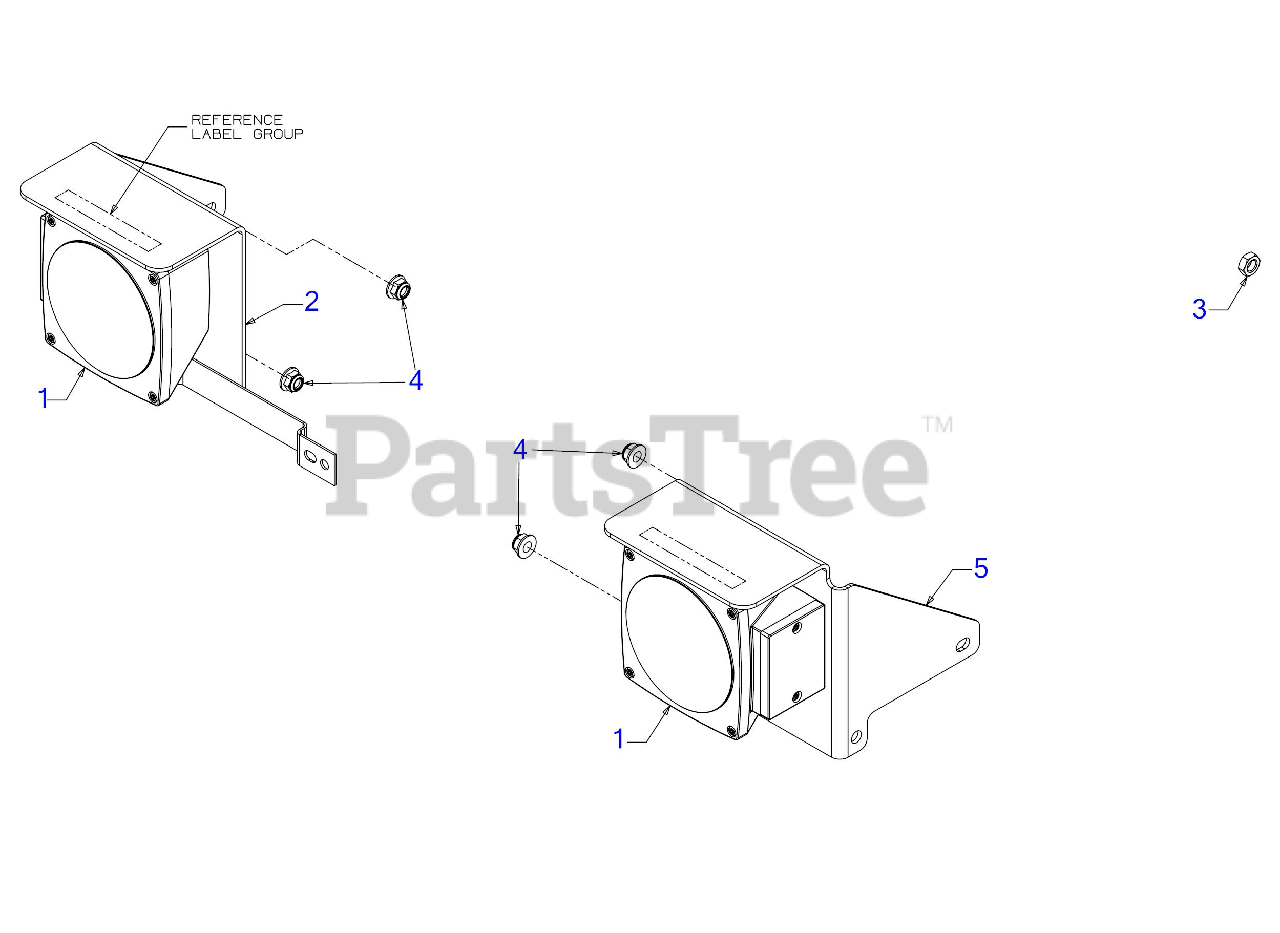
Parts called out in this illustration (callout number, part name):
1	TAIL LIGHT ASSEMBLY
2	LIGHT BRACKET ASSEMBLY (LH)
3	HEX NUT
4	FLANGE LOCK NUT 5/16-18
5	LIGHT BRACKET (RH)
